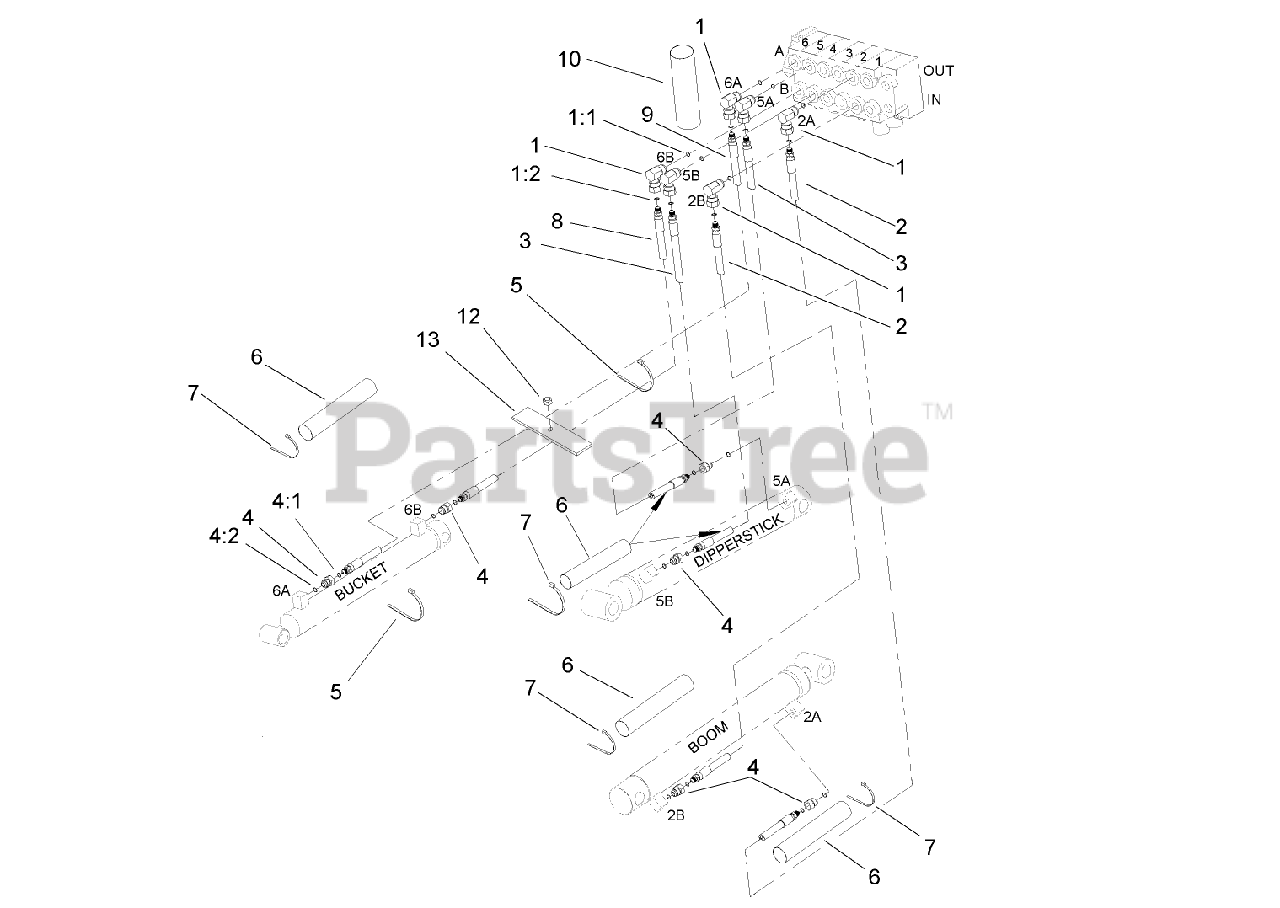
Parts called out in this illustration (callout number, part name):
1	FITTING-ELBOW 90
1:1	O-RING
1:2	O-RING
2	HYDRAULIC HOSE ASM
3	HYDRAULIC HOSE ASM
4	FITTING-STRAIGHT
4:1	O-RING
4:2	O-RING
5	TIE-CABLE
6	SLEEVE-HOSE
7	TIE-CABLE
8	HOSE-HYD
9	HYDRAULIC HOSE ASM
10	SLEEVE-HOSE
12	NUT-LOCK
13	RETAINER-HOSE
